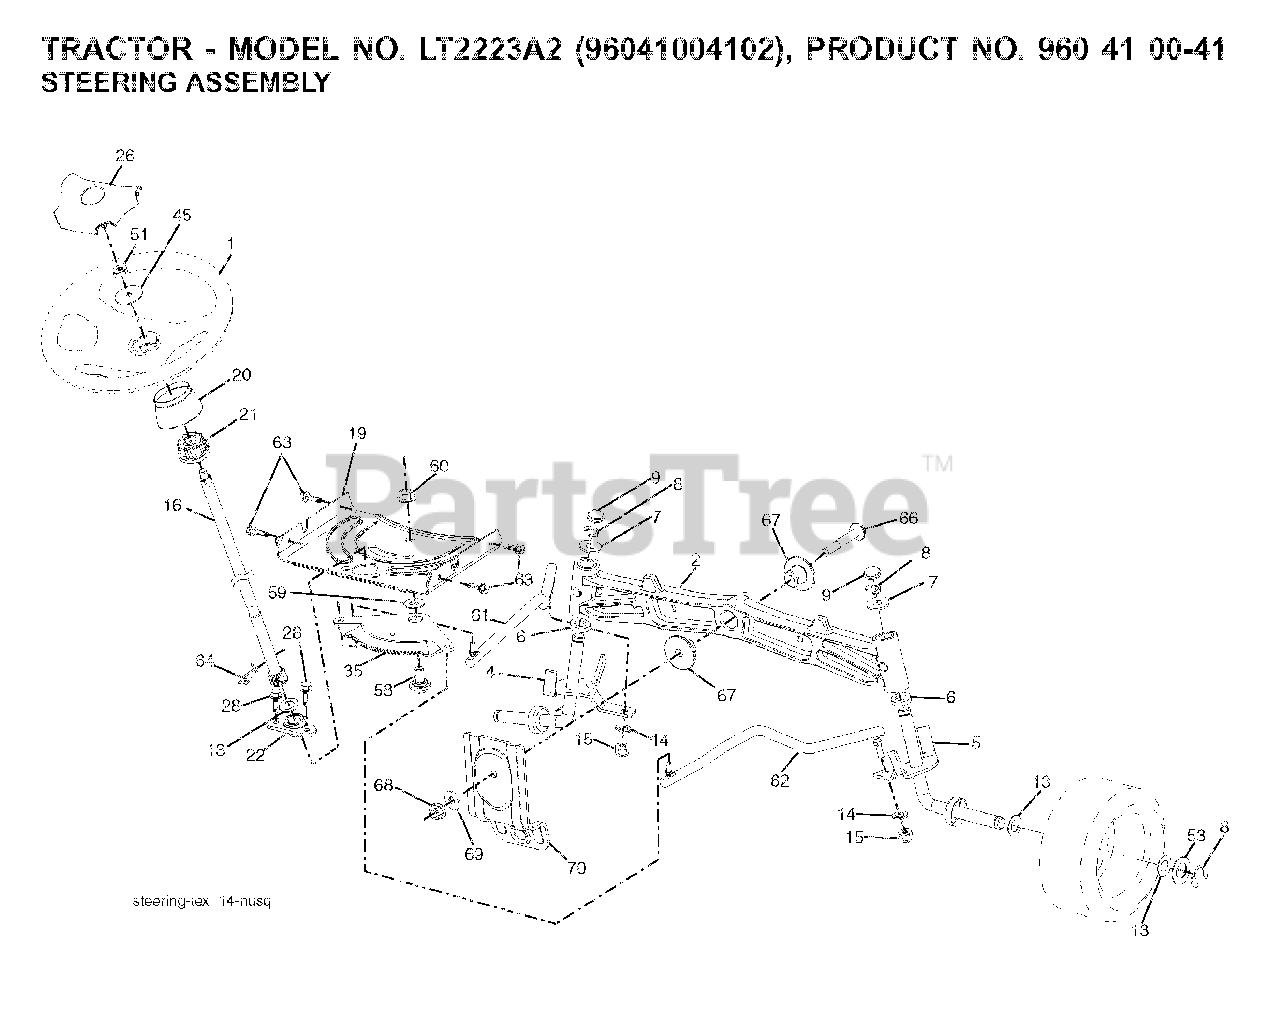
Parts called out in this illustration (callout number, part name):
1	WHEEL.STEERING.PREM.2.BLK
2	AXLE.CAST.IRON
8	RING CLIP
9	CAP.SPINDLE
14	WASHER, LOCK 3/8
15	NUT CROWNLOCK 3/8-24
16	SHAFT.STEER.STEALTH.DD
19	PLATE.STEER.DDL.NLT/NG
20	BOOT.STEERING.
21	ADAPTER, WHEEL STNG..
22	BUSHING.ASM.STEERING.A
26	INSERT.CAP.STRG.WH.BLACK
28	SCREW, 3/8-16X3/4
35	GEAR.SECTOR.PLATE.DDL.
45	WASHER.11/32
51	NUT.HEX.1/2-20
53	WASHER.HARDENED
58	BOLT.SHOULDER.SECTOR.P
59	WASHER.THURST.SECTOR.S
60	NUT FLANGE LOCK 5/8-11
61	DRAGLINK.LH.BALLSTUD.D
62	DRAGLINK.RH.BALLSTUD.D
63	SCREW
64	RETAINER.CLIP.SPRING.S
66	BOLT HEX FGHD 7/16-14 X 3 SERR
67	BUSHING.PM.FRONT AXLE
68	NUT.LOCK.FLANGE.7/16
69	WASHER.1.5X.505X.118
70	BRKT.DECK.SUSPENSION.F
